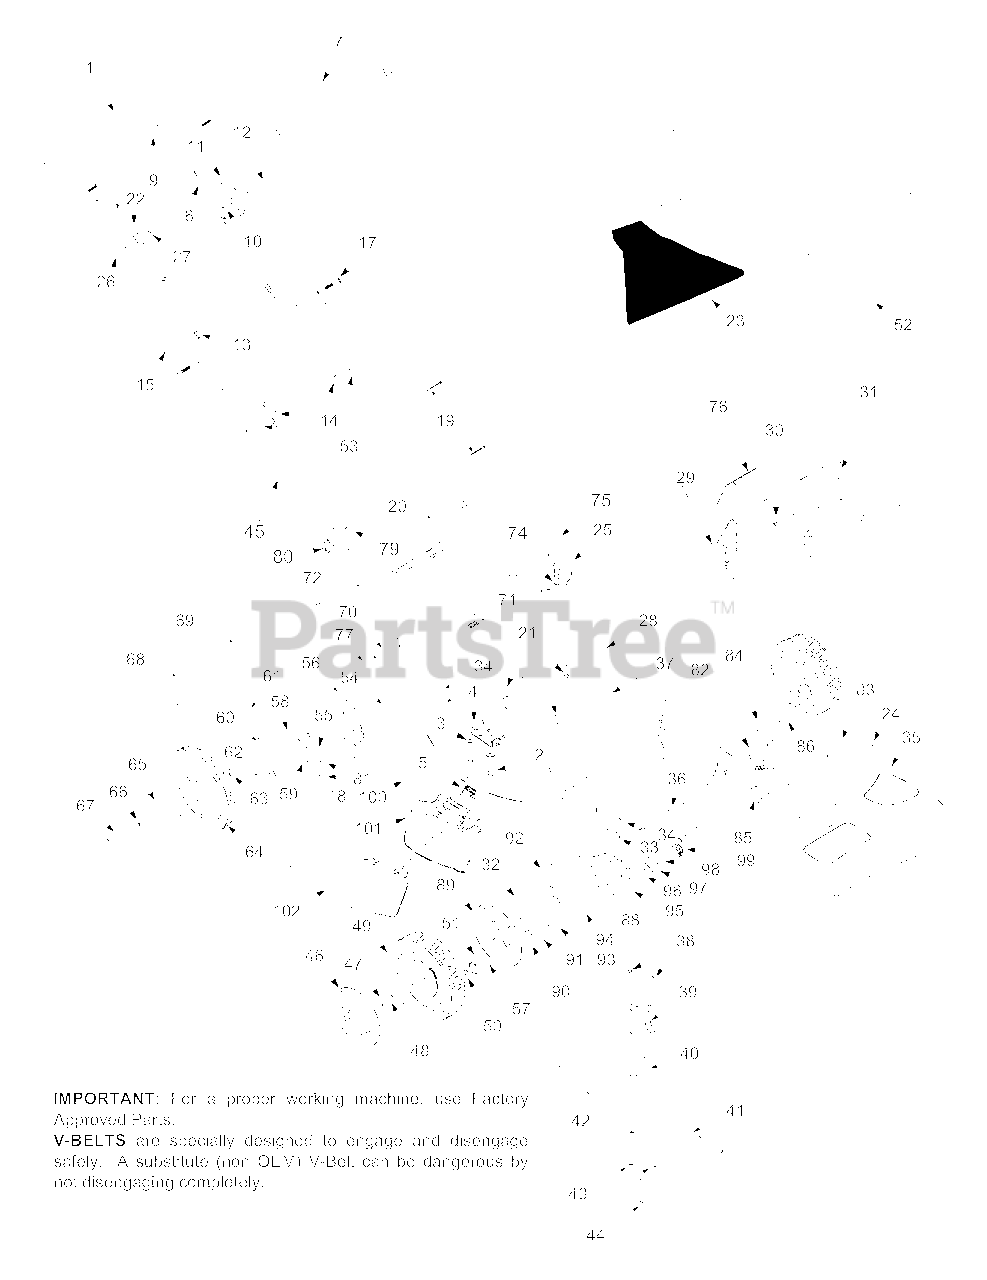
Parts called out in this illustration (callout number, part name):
2	TT Screw 1/4-20 x 0.5
3	Bell Washer
5	Torsion Spring
6	Throttle Cable
10	Hex Lock Nut, 1/4-20
11	Throttle Housing w/ Choke
12	Oval C-Sunk Screw 1/4-20 x 1.31
13	Handle Knob
14	Handle Knob
15	Eye Bolt
17	Carriage Bolt 5/16-18 x 2.0
18	RH Bracket Ass'y
19	Cable Tie
20	Cotter Pin
21	Self-Tapping Sems Screw
22	Drive Cable
23	Grassbag Assembly (Half Sail)
24	Shoulder Screw # 12 -24
25	Engine Spacer
26	Hex Bolt 1/4-20 x 1.5
27	Lock Nut 1/4-20
30	Screw AB: 1/4-14: .625
32	Hex Screw 3/8-16 x .75
33	Bell Washer .39 x 1.13 x .062
34	Hex Nut 3/8-16
35	Transmission Cover (Yellow)
38	Hex Nut 1/4-20
39	Drive Pulley
40	Blade Adapter
41	21" Mulching Blade
42	Flat Washer .516 x 1.5 x .134
43	Hex Screw 1/4-20 x 1.50
44	Hex Screw 3/8-24 x 2.50
46	Hub Cap
47	Cotter Pin
48	Flat Washer
49	Wheel 8 x 2
50	Snap Ring
51	Gear 14T LH FWD
53	Saddle Washer
54	Hex Flange Lock Nut 3/8-16
55	Hex Scr. w/Washer 1/4-14 x .625
57	Dowel Pin
58	Pan Head Screw
59	RH Pivot Bar
60	Height Adj. Lever
61	Foam Grip
62	Shoulder Scr .500 Dia. x .434
63	Washer .401 x .870 x .063
64	Wheel, 14 x 2
65	Spring Washer .50 I.D. x 1.0 O.D.
66	Flat Washer .510 x 1.373 x .04
67	Shoulder Screw
68	Wire
69	Rear Trailing Shield
70	Pivot Rod
71	Torsion Spring
75	Shoulder Screw
76	Plastic Mulching Plug
77	Spacer .375 x .50 x 1.02" Lg.
79	Carriage Bolt 1/4-20
80	Wing Nut
81	Hex Bolt 3/8-16 x 1.0"
82	Belt Tension Spring
83	Slev. Spacer RH
84	Input Pulley
85	Transmission Assembly
86	Roll Pin
88	Height Adjustment Assembly RH
89	Wheel Dust Cap
90	Snap Ring
91	Washer
92	Adjustment Knob
93	Front Lever RH
94	Pivot Plate Assembly
97	Bearing Support
98	Bearing Sleeve
99	Bearing Retainer
100	Hinge Pin
101	Mulch Plug (Hinged)
102	Chute Deflector
